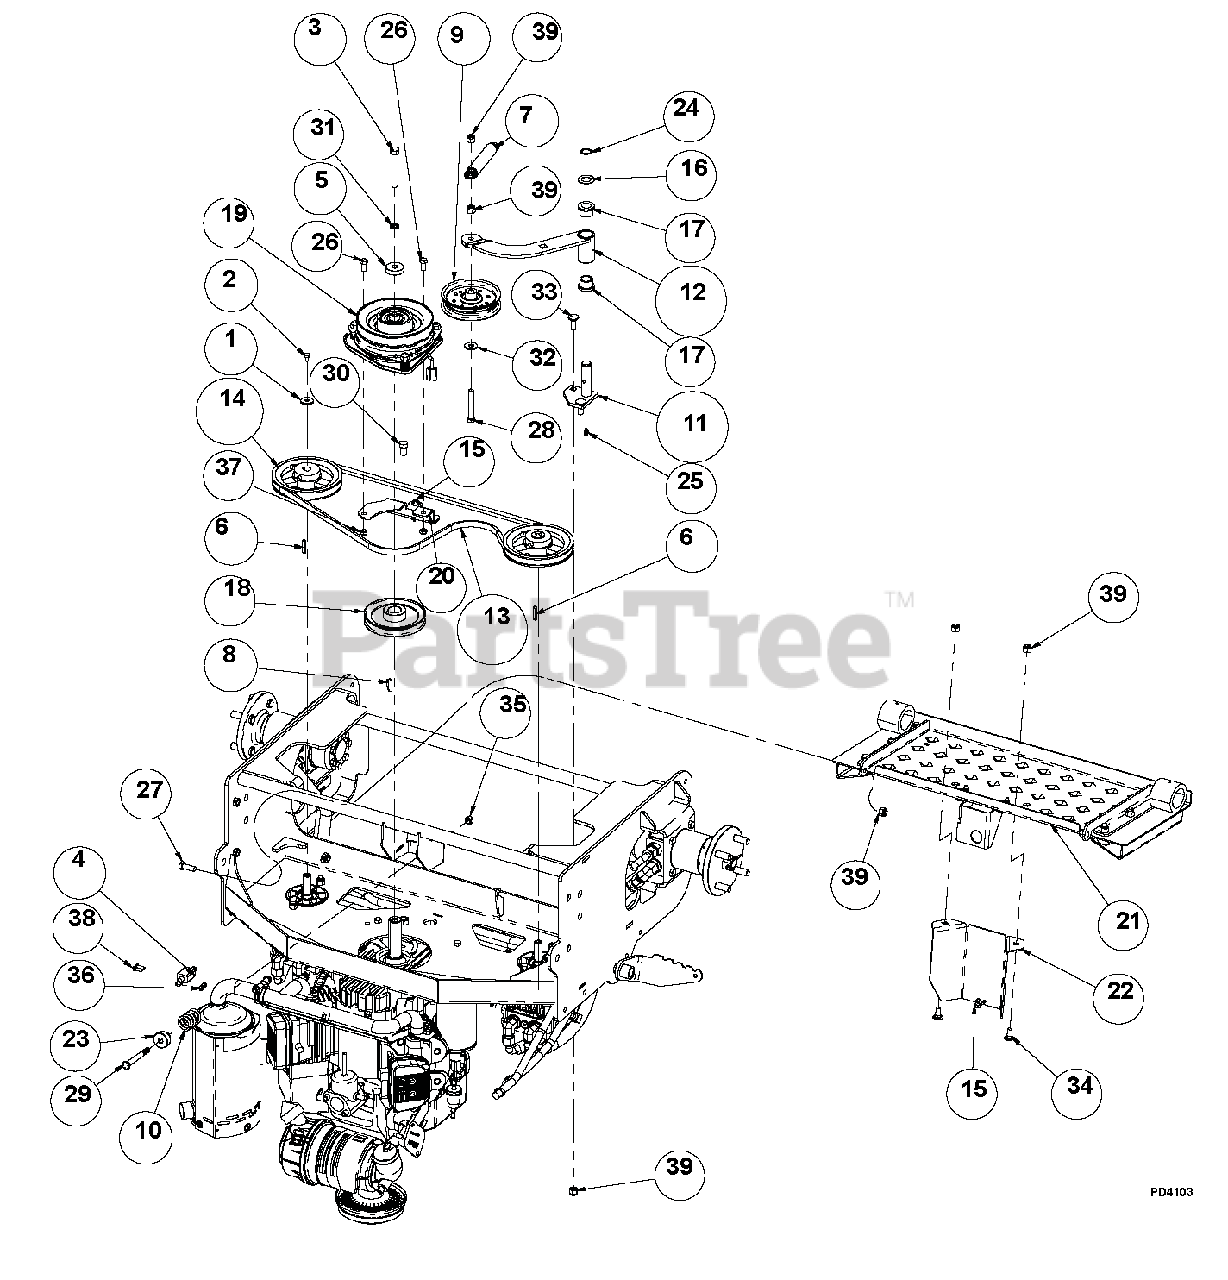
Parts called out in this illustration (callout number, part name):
1	WSHR-LK .250X.077 HVY YWZC
2	BOLT, M6X1.00X10 HEX 8.8 Y
3	BLT-HEX .44-20X3.00 GR5 YWZC
4	SWITCH
5	SPACER, PTO CLUTCH
6	KEY, .250 X .250 X .995 TPR
7	SPRING, IDLER
8	KEY, .250 X .250 X .995 TPR
9	IDLER
10	SPRING
11	IDLER POST
12	IDLER ARM
13	V-BELT
14	PULLEY, RH PUMP SET SCREW INCL
15	TIE WRAP, BLACK LG 7.31
16	BUSHING, MACH .750X1.25X.048 Y
17	BSHG-FLG .750X1.000X.750X1.250
18	PULLEY, V-BELT 4.78PD X 1.000
19	CLUTCH ASSY, OGURA
20	PLATE, CLUTCH DOG
21	ASSEMBLY, FOOT PLATE
22	SCREW, CYLINDER, D912 M 4X 5
23	WASHER, SPRING Y
24	RG-RTNG-EXT .750X.042
25	GREASE ZERK, 1/4-28 STR .69 LG
26	@BLT-HEX .31-18X.75 GR5 YWZC
27	@BLT-HEX .38-16X1.00 GR5 YWZC
28	@BLT-HEX .38-16X2.50 GR5 YWZC
29	@BLT-HEX .38-16X3.25 GR5 YWZC
30	@BLT-HEX .44-14X.75 GR5 YWZC
31	WASHER, .438 MED SPRG LOCK Y
32	@WSHR-FL-STL.438X1.00X.083 YWZ
33	@BLT-RDHDSQNK .38-16X1.00 G5YZ
34	@BLT-RDHDSQNK .38-16X.75 G5YZ
35	@NUT-HEX .31-18 YWZC
36	@NUT-LK-NYL 10-24 W/INSRT YWZC
37	@NUT-LK-NYL .312-18 YWZC
38	SCR-MCH 10-24X.62 P/HD
39	@NUT-LK-NYL .38-16 YWZC
